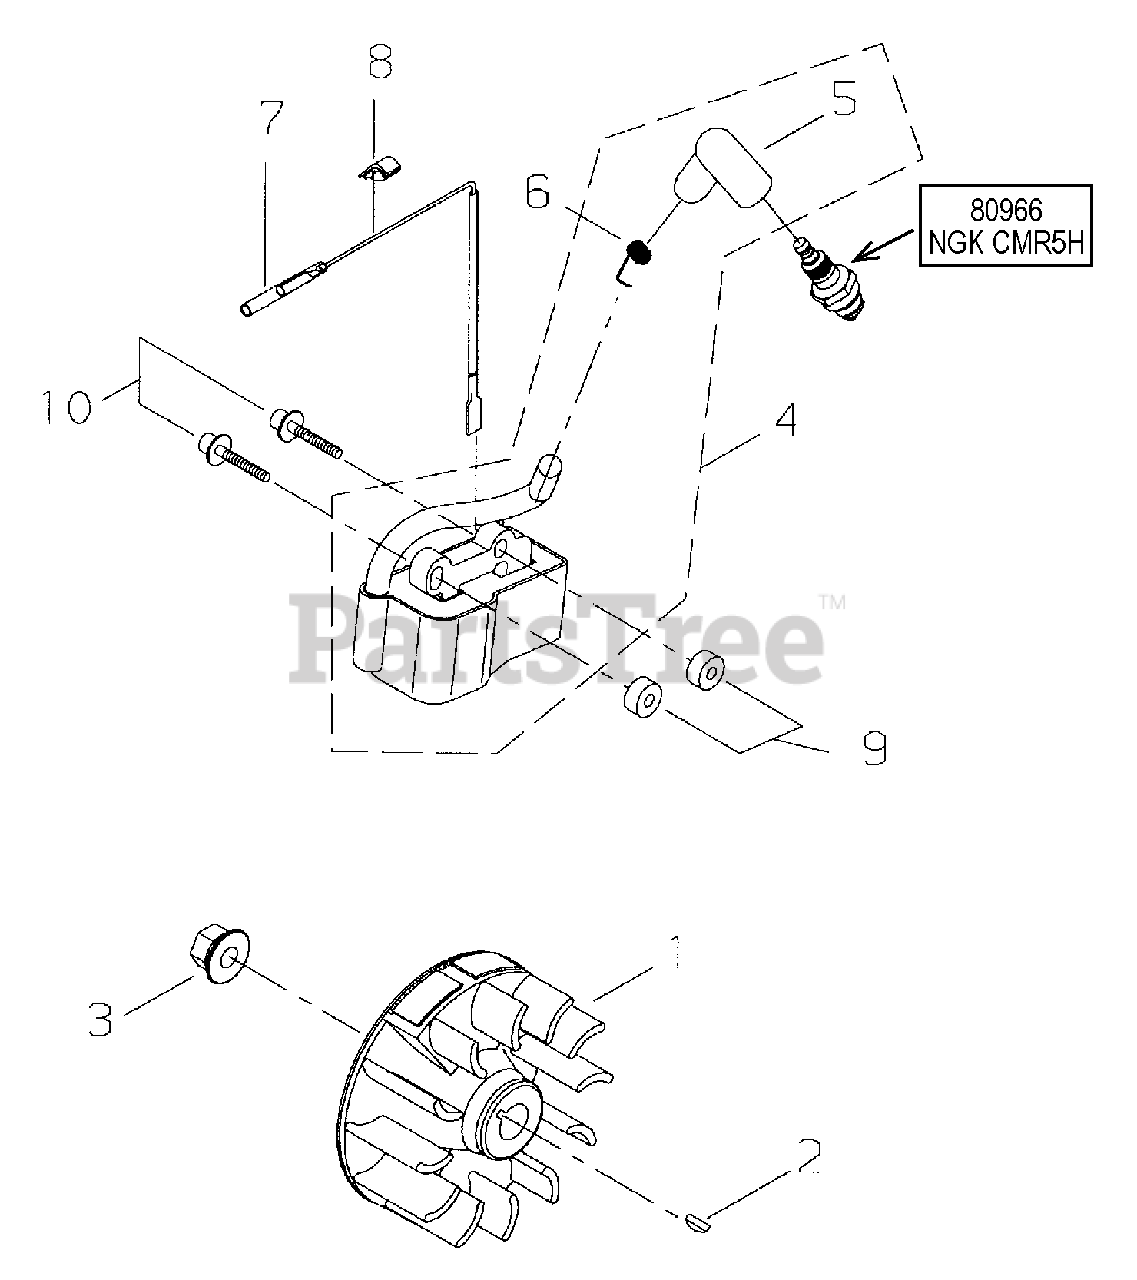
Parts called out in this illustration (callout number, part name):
1	FLYWHEEL
2	KEY - 3X10
3	NUT - 8
4	IGNITION COIL ASSY
5	CAP, SPARK PLUG
6	TERMINAL, SPARK PLUG CAP
7	LEAD - IGNITION
8	GROMMET
9	INSULATOR
10	SCREW - 4X26
